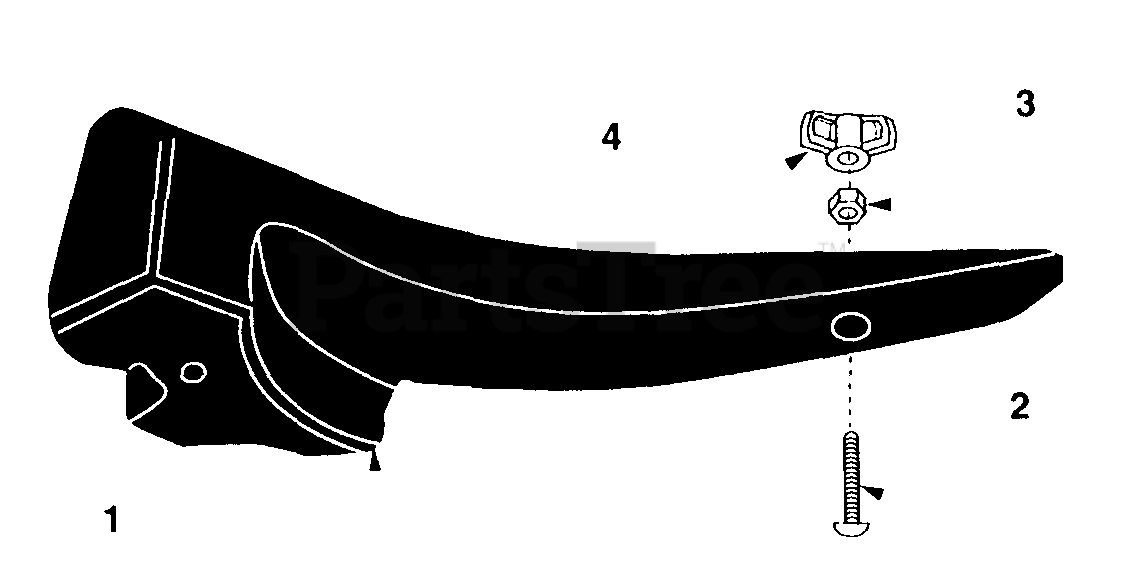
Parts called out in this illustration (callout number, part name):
1	Mulching Plug
2	16.28" 3 in 1 Blade
3	14.88" 3 in 1 Blade
4	Machine Screw (1/4")
